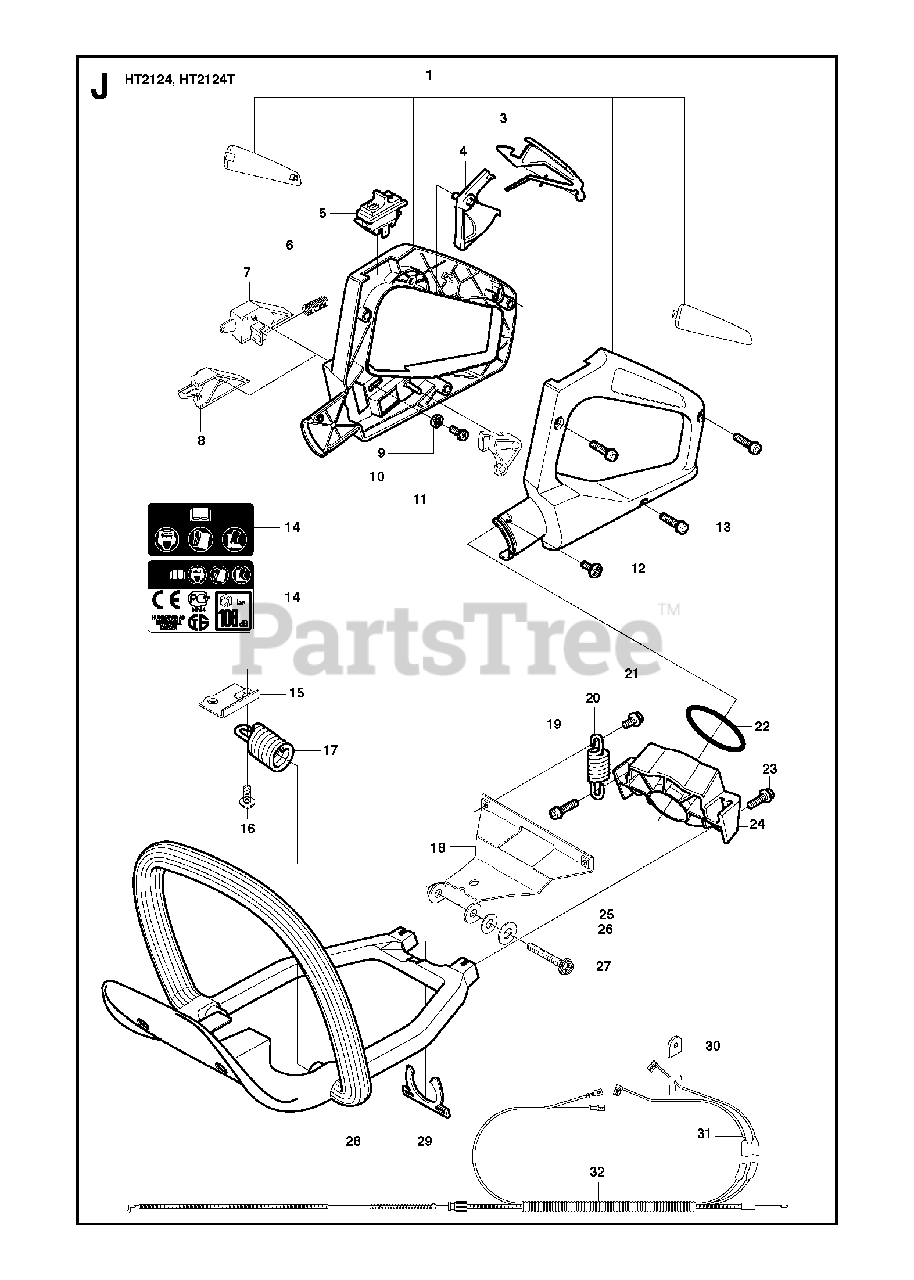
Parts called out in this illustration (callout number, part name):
5	START/STOP SWITCH
6	SPRING
11	PAWL
14	LABEL
15	ROD/STAY
16	SCREW M5 X 10
17	VIBRATION ABSORBER
18	%ROD
20	VIBRATION ABSORBER
21	SCREW M5 X 10
26	WASHER - M6
31	SHORTING LEAD
32	%WIRING ASSEMBLY
